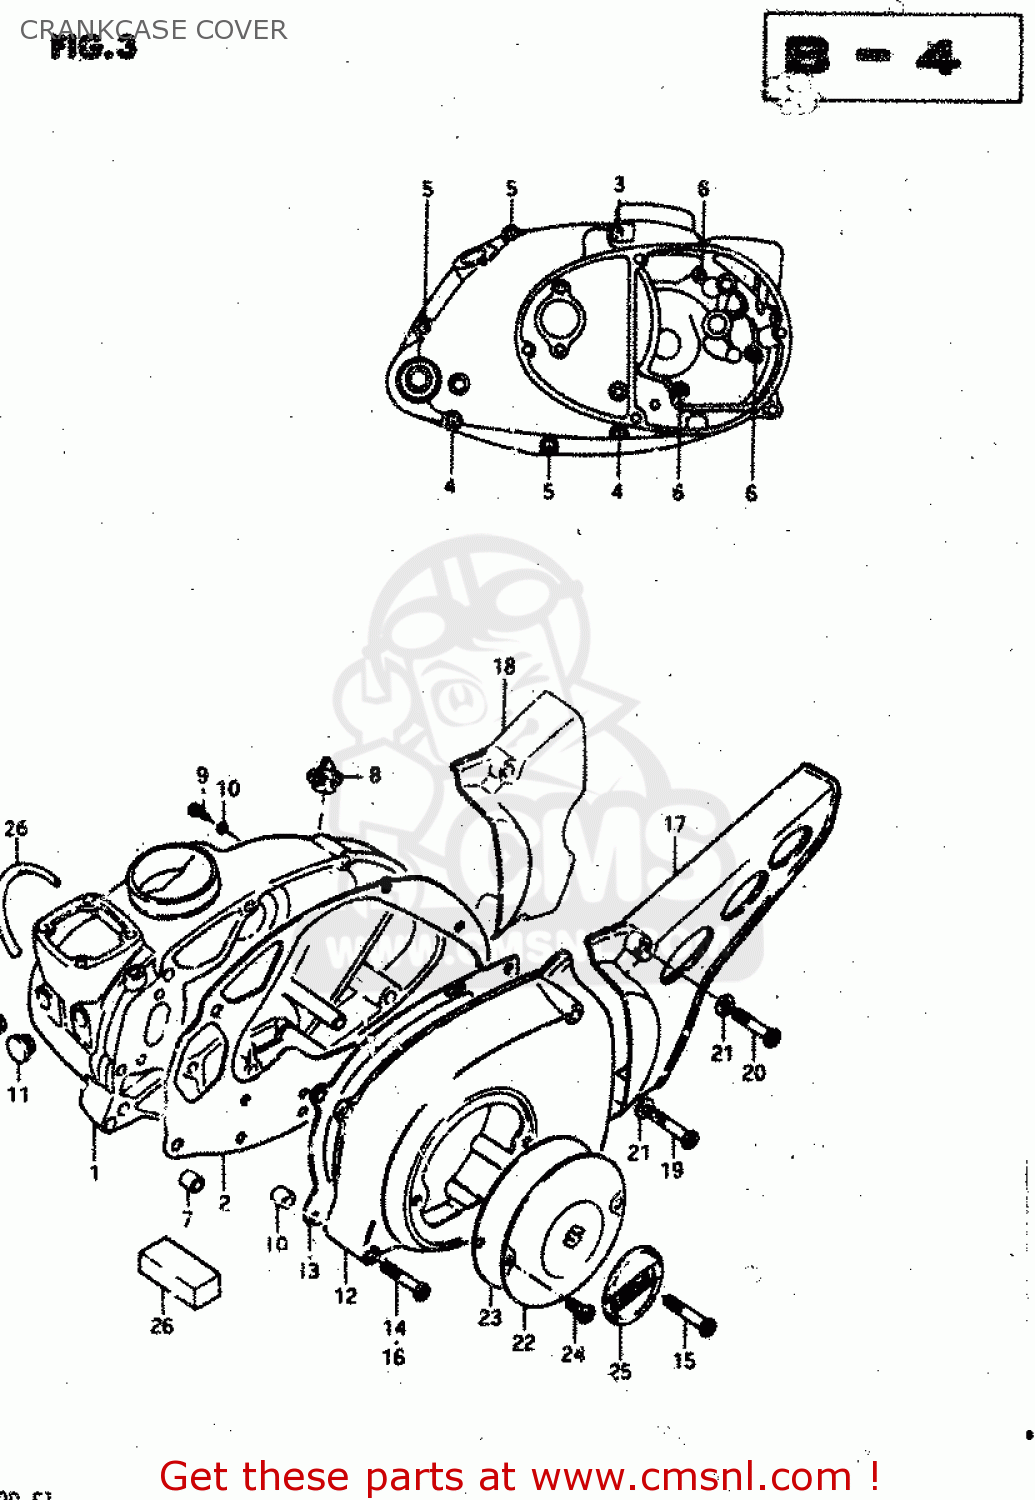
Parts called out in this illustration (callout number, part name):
1	COVER, CLUTCH
2	GASKET,CLUTCH (MCA)
3	SCREW 6X80
4	SCREW 6X65
5	SCREW
6	SCREW
7	PIN
8	PLUG,OIL FILTER
9	SCREW(6X10)
10	GASKET(6.2X11X1) (NAS)
11	Plug
12	COVER, MAGNETO
13	GASKET,MAGNETO COVER (NAS)
14	SCREW
15	SCREW
16	SCREW 6X30
17	COVER,ENGINE SPROCKET
18	COVER,SPROCKET
19	SCREW
20	SCREW 6X30
21	WASHER
22	CAP,MAGNETO INSPECTION
23	GASKET,MAGNETO INSPECTION CAP (NAS)
24	SCREW
25	EMBLEM,CARB INSPECTION CAP
26	SEAL,DUST
